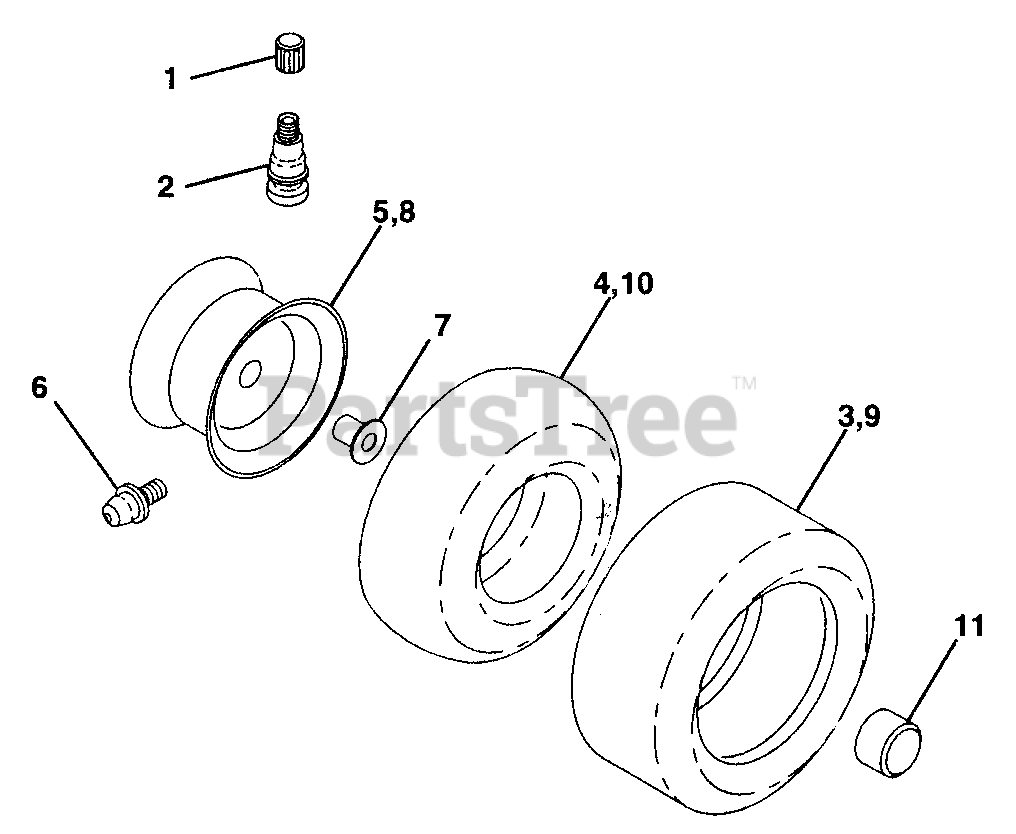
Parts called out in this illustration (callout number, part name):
1	Cap Valve Tire
2	Stem Valve
3	Tire F Ts 15 X 6 0 - 6 Service
4	Tube Front (Service Item Only)
5	Rim Asm 6" front Service
6	Fitting Grease (Front Wheel Only)
7	Bearing Flange (Service Item Only)
8	Rim Asm 8" rear Service
9	Tire R Ts 18x9 5-8 C Service
10	Tube Rear (Service Item Only)
11	Cap Axle Blk 1 50 X 1 00
